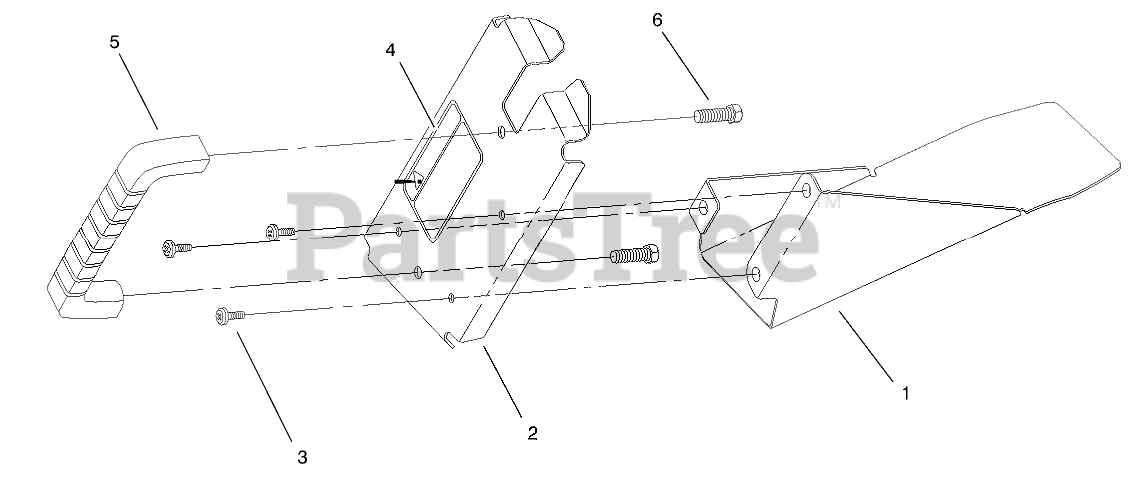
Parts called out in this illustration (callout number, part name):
1	Shield-Discharge Plug
2	Cover-Discharge Plug
4	DECAL - WARNING
5	HANDLE-DOOR
6	SCREW-HWH
